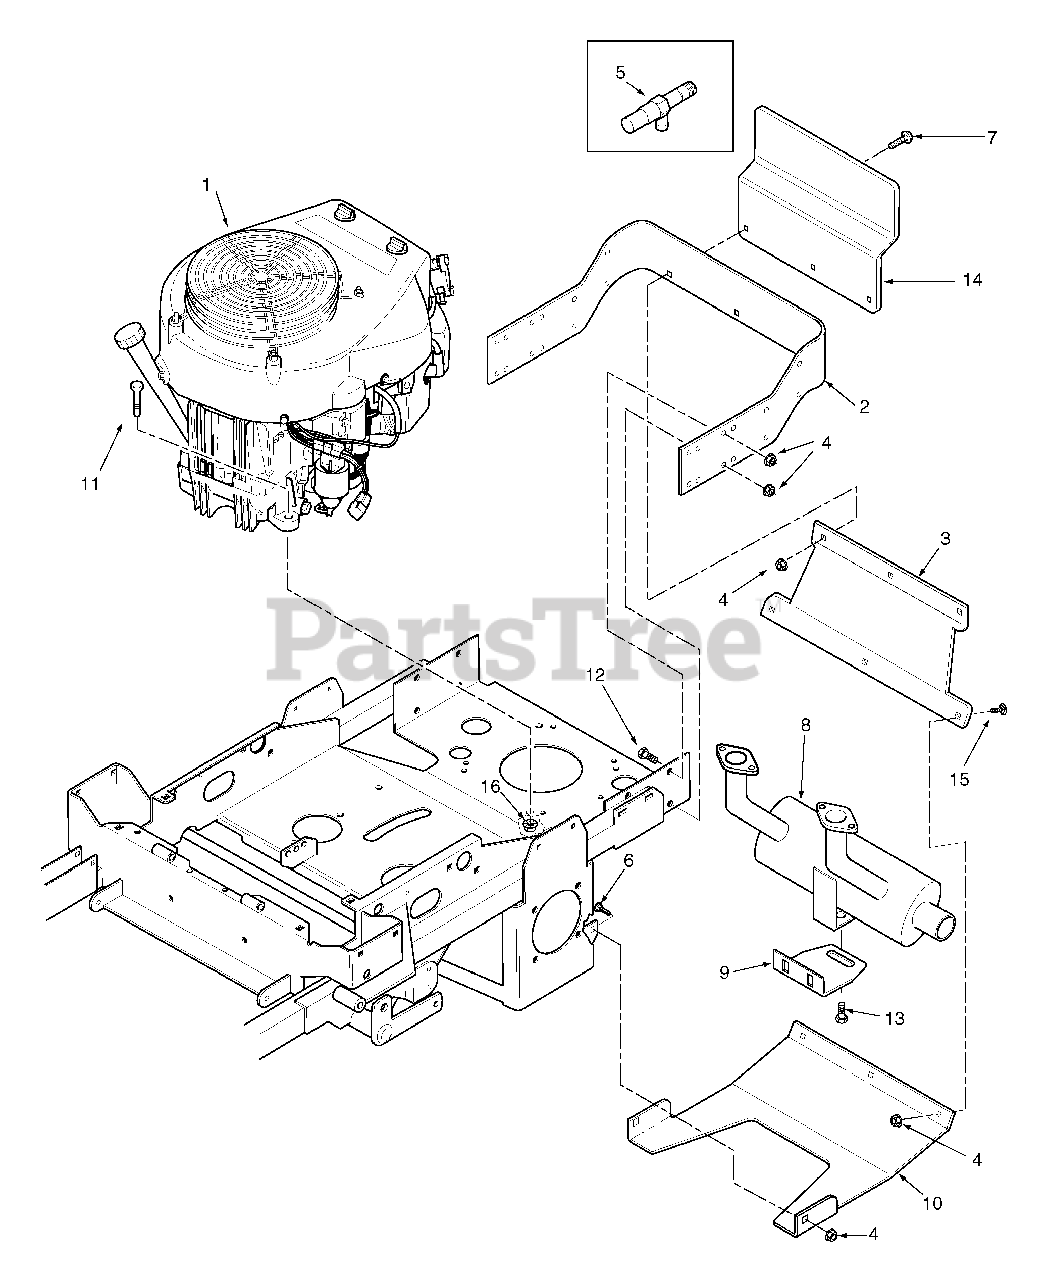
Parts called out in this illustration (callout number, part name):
1	Engine, 27HP Kohler
2	Bumper, Rear
3	Weight, Rear (Shield)
4	Nut, Serr. Flange 3/8-16
5	Extension, Oil Drain 4" - Kohler, Kawasaki 26HP
6	Bolt, Carr. 3/8-16 x 1"
7	Bolt, Hex Head 3/8-16 x 1-1/4"
8	Muffler - Kohler
9	Bracket, Muffler
10	Plate, Skid
11	Bolt, Hex Head 5/16-18 x 1-1/2"
12	Bolt, Hex Head 3/8-16 x 1"
13	Screw, 5/16-18 x 3/4"
14	Guard, Carb Inlet
15	Bolt, Hex Head 3/8-16 x 1-1/4"
16	Nut, Serr. Flange 5/16-18
